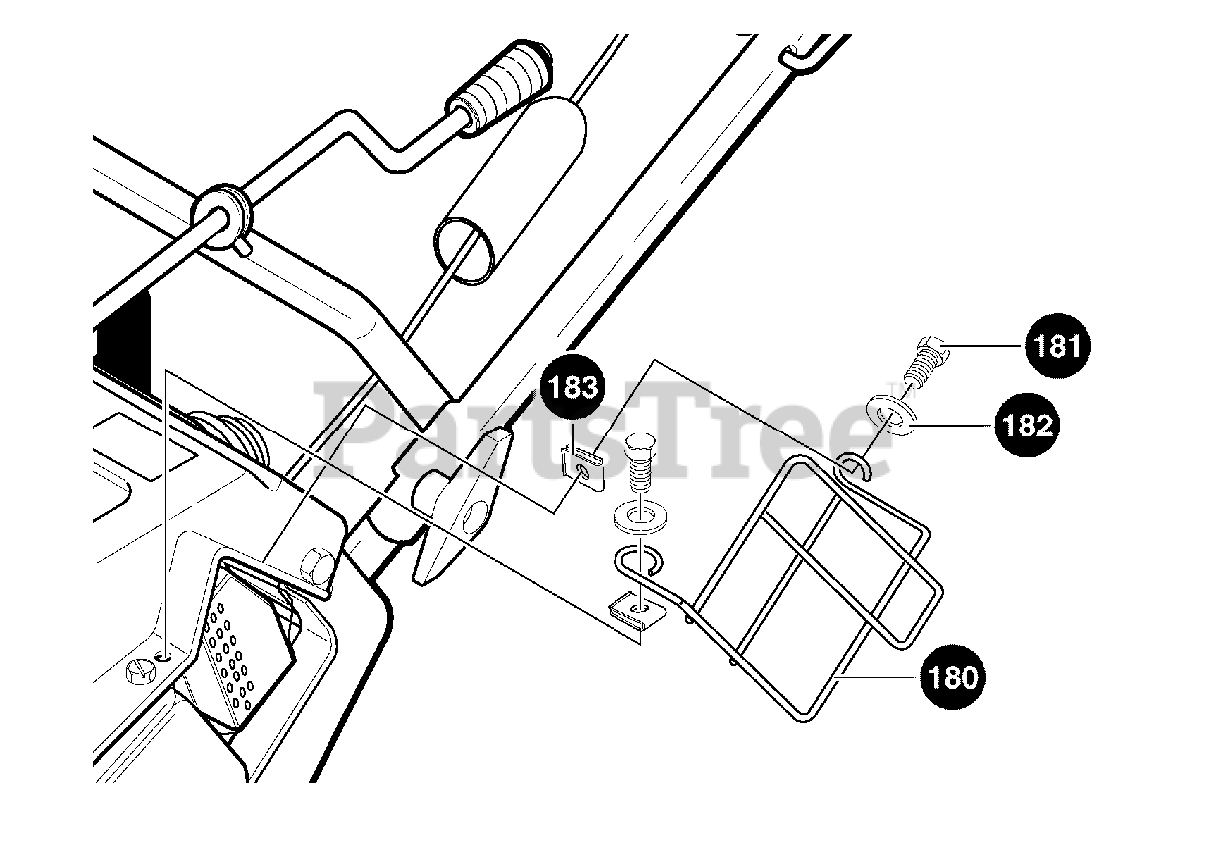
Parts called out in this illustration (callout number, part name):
180	GUARD, MUFFLER -EXPT
181	SCREW
182	WASHER, FLAT
